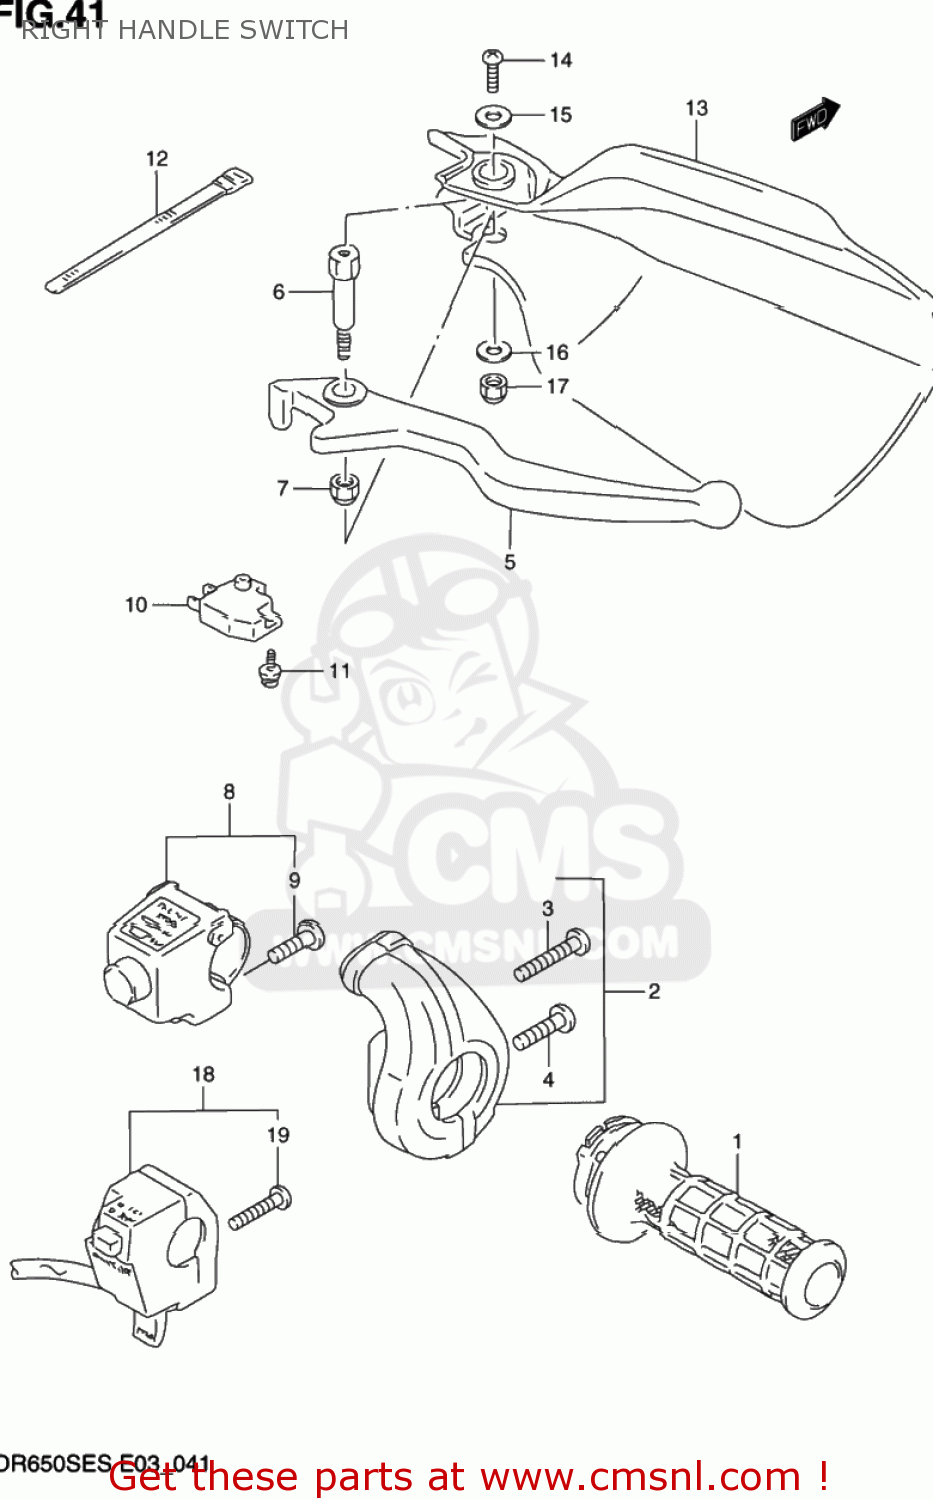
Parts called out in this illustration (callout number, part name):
1	GRIP,THROTTLE
2	CASE ASSY,THROTTLE
3	SCREW(5X25)
4	SCREW 5X20
5	LEVER,BRAKE
6	BOLT,BRAKE LEVER PIVOT
7	NUT
8	SWITCH ASSY, HANDLE RH
9	SCREW
10	SWITCH ASSEMBLY,STOP
11	SCREW
12	CLAMP(L:120)
13	COVER,KNUCKLE,R
14	SCREW
15	WASHER (5.5X16X1.2)
16	WASHER (6.5X17X1.6)
17	NUT 6MM
18	SWITCH ASSY,HANDLE,R
19	SCREW, 5X45
